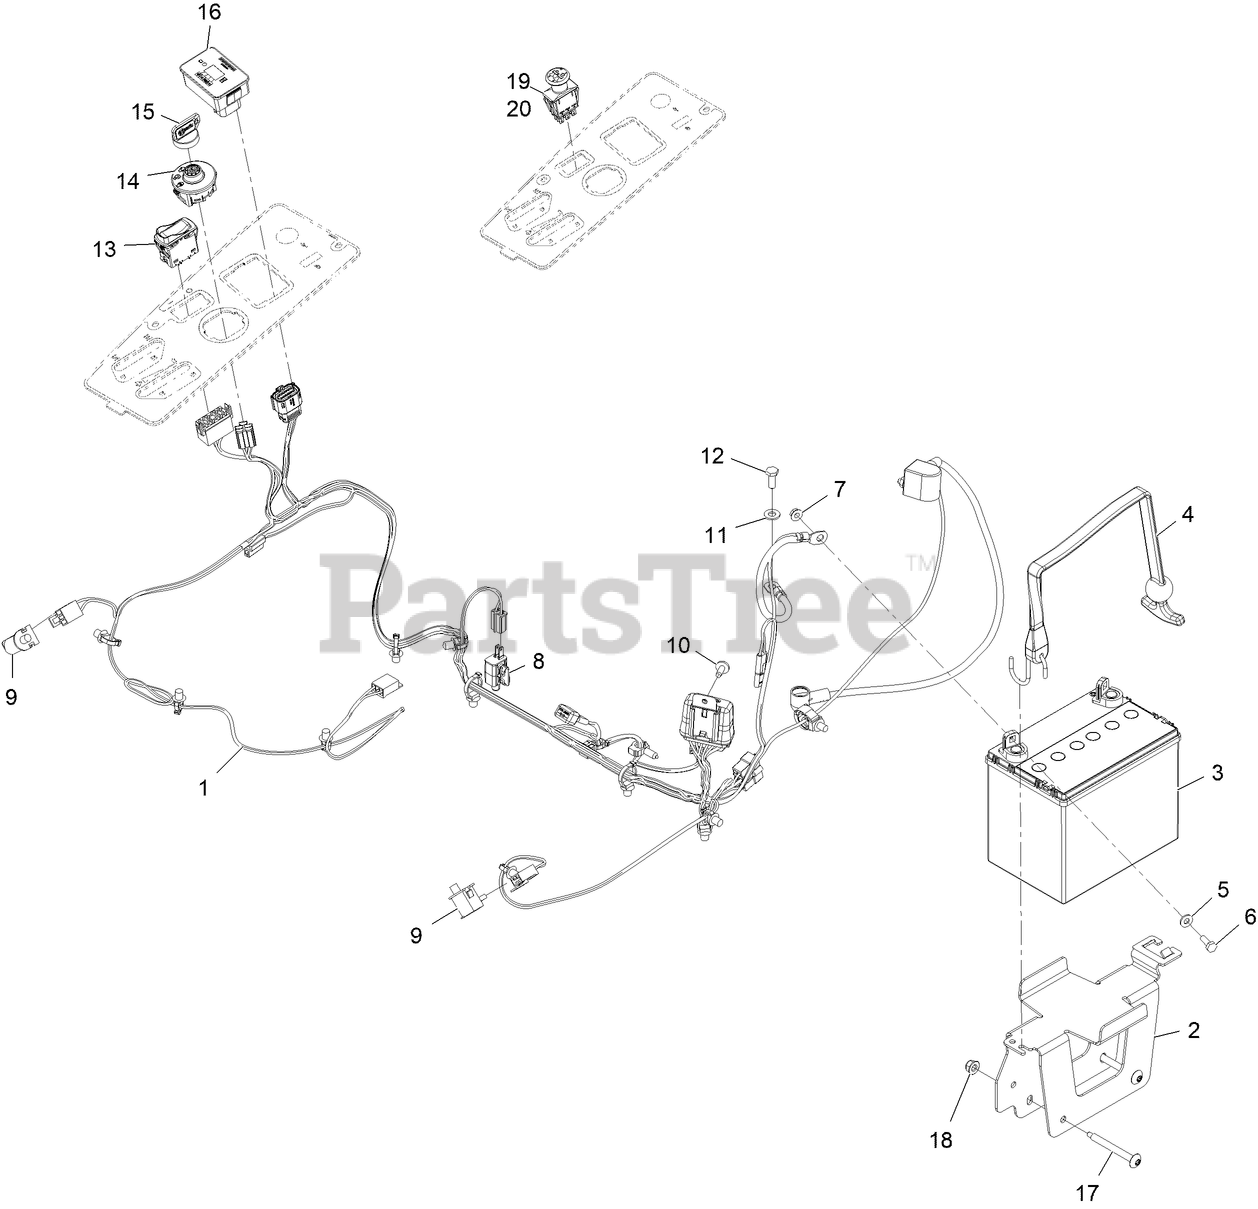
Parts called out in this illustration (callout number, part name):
1	Harness-Wire
2	TRAY-BATTERY
3	Battery
4	STRAP, BUNGEE
5	WASHER-FLAT
6	SCREW-HH
9	SWITCH-BAIL
10	SCREW-TORX
11	WASHER-PLAIN
12	SCREW-HH
13	SWITCH-ROCKER, ON-NONE-ON
14	SWITCH-IGNITION
15	KEYS-IGNITION (SPARE PAIR
15	KEY-IGNITION
16	MODULE ASM
17	SCREW-TORX
18	NUT-HF, NI
19	SWITCH-PTO
